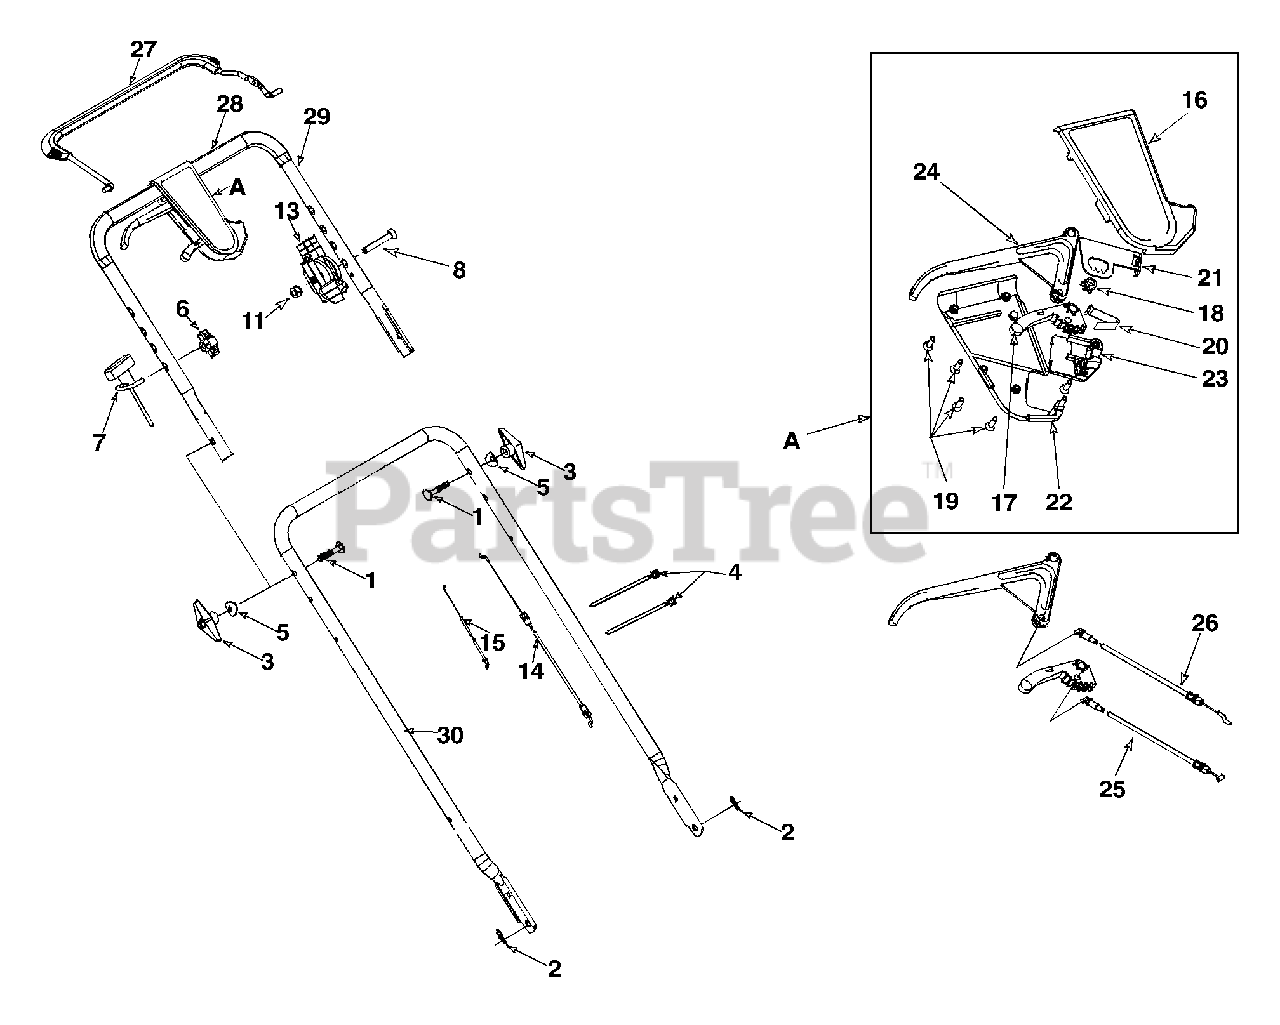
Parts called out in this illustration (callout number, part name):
1	Bolt Curv. Carr. 5/16-18 x 2.0
2	Cotter Pin .072 x 1.12 Lg.
3	Knob Assembly
4	Strap
5	Wash. Sad. .320 ID x.830 OD
6	Knob Handle ERS - 1/4-20
7	Rope Guide Eyebolt
8	Oval C-Sunk Screw
11	Nut 1/4-20 Top lock Nut Insert
13	Control Housing
14	Control Cable 44" Lg.
16	Upper Control Housing
17	6 Speed Shift Lever
18	Gear Insert
19	CSunk Tap Scr #10 x .75 L
20	Shift Lever Spring
21	6 Spd. Rack Cable Brkt.
22	Lower Control Housing
23	Cable Mounting Cap
24	Control Lever
25	6 Spd. Cable
26	S.P. Cable
27	Control Handle
28	Foam Grip
